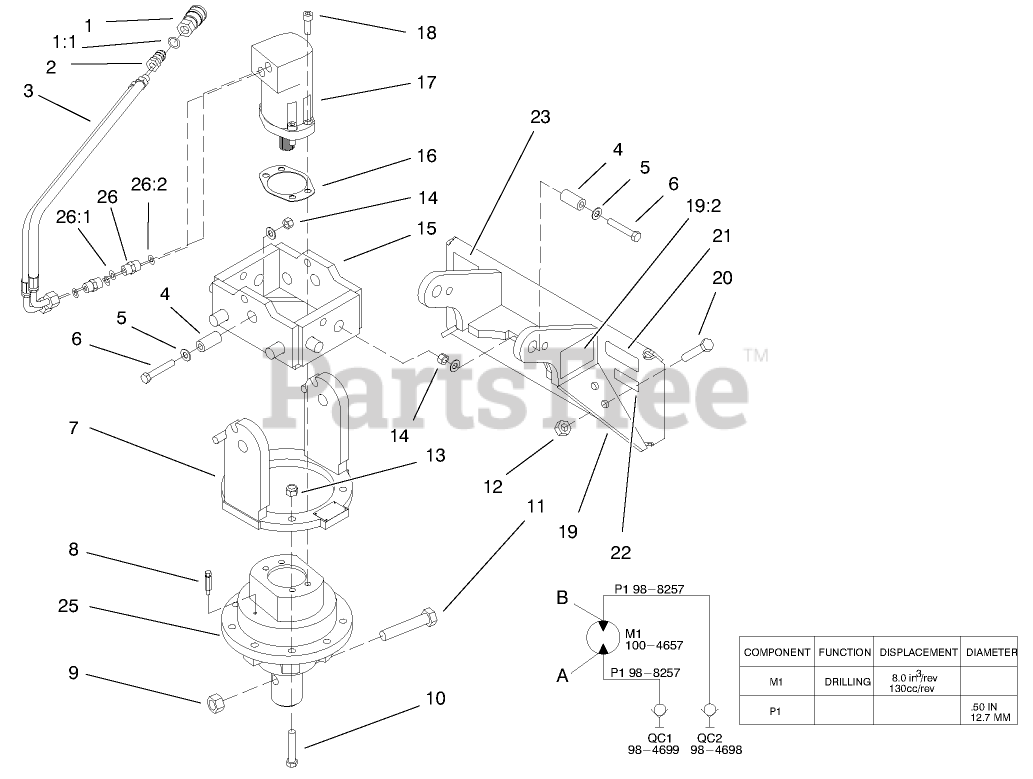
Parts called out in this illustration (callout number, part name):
1	FEMALE-DISCONNECT, QUICK
1:1	SEAL KIT
2	MALE-DISCONNECT, QUICK
3	HOSE - HYDRAULIC
4	PIN - PIVOT
5	WASHER-FLAT
6	SCREW-HH
7	HOUSING - DRIVE
8	BREATHER ASM
9	NUT-HEX
10	SCREW-HH
11	SCREW
12	NUT-HEX
13	LOCKNUT
14	NUT-LOCK, NI
15	SWIVEL GIMBEL ASM
16	GASKET
17	HYDRAULIC MOTOR ASM
18	SCREW-HSH
19	AUGER MOUNT ASM,
19:2	DECAL-WARNING
20	SCREW-HH
21	DECAL-ATTACHMENT, DINGO
22	DECAL-INFO
23	DECAL
25	DRIVE-GEAR, PLANETARY
26	FITTING-STRAIGHT
26:1	O-RING
26:2	O-RING
